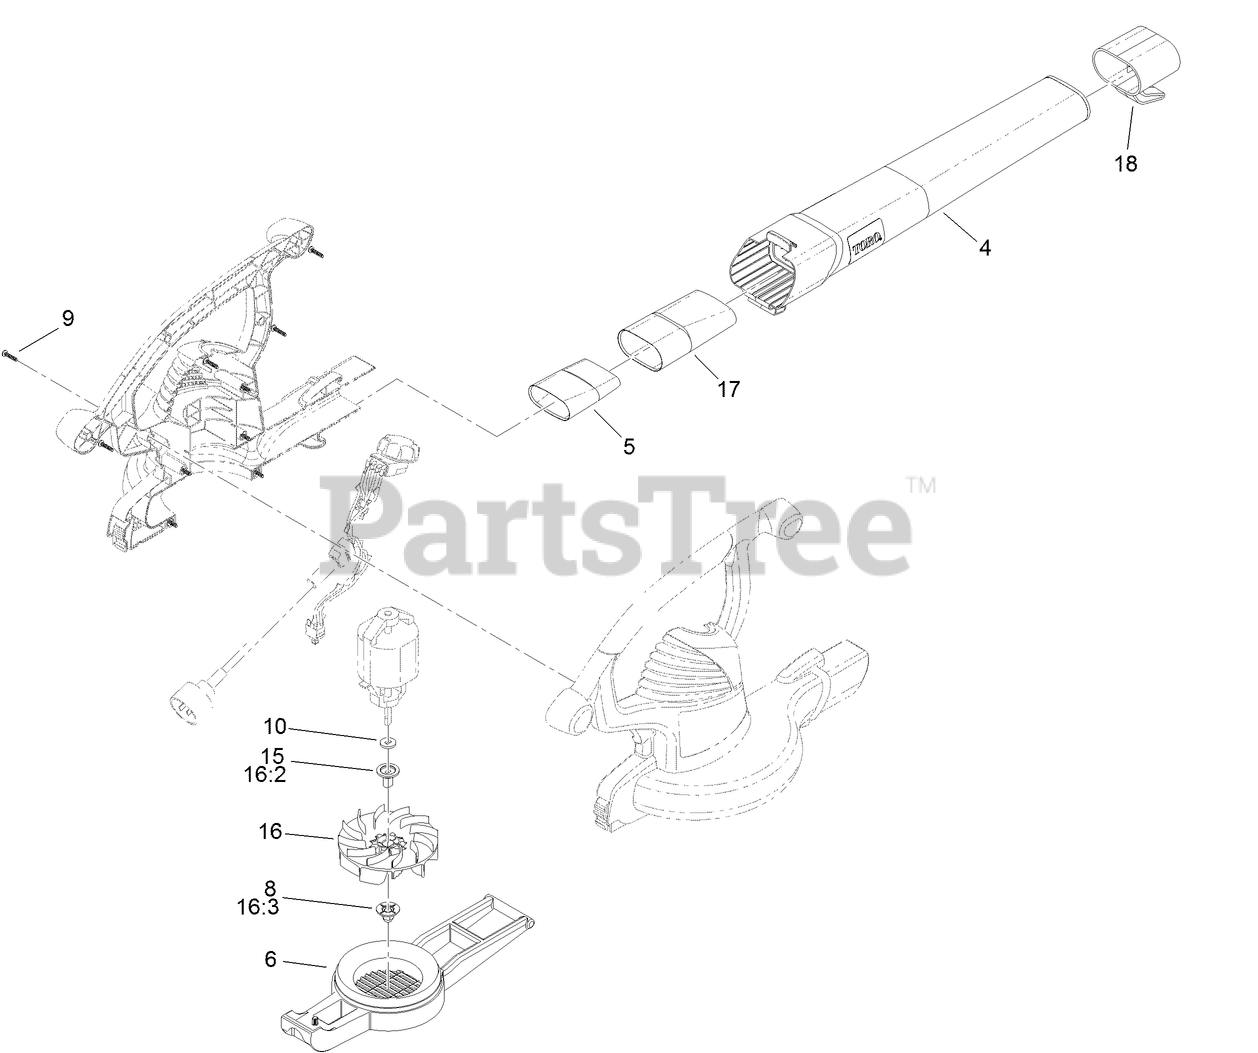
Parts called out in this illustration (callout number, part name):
4	TUBE-BLOWER
5	TUBE-INSERT, ULTRA
6	COVER-INLET
8	NUT-IMPELLER
9	SCREW-PPH
10	WASHER-IMPELLER
15	INSERT-IMPELLER
16	IMPELLER ASM
16:2	INSERT-IMPELLER
16:3	NUT-IMPELLER
17	TUBE-INSERT
18	ADAPTER-WRAP, CORD
